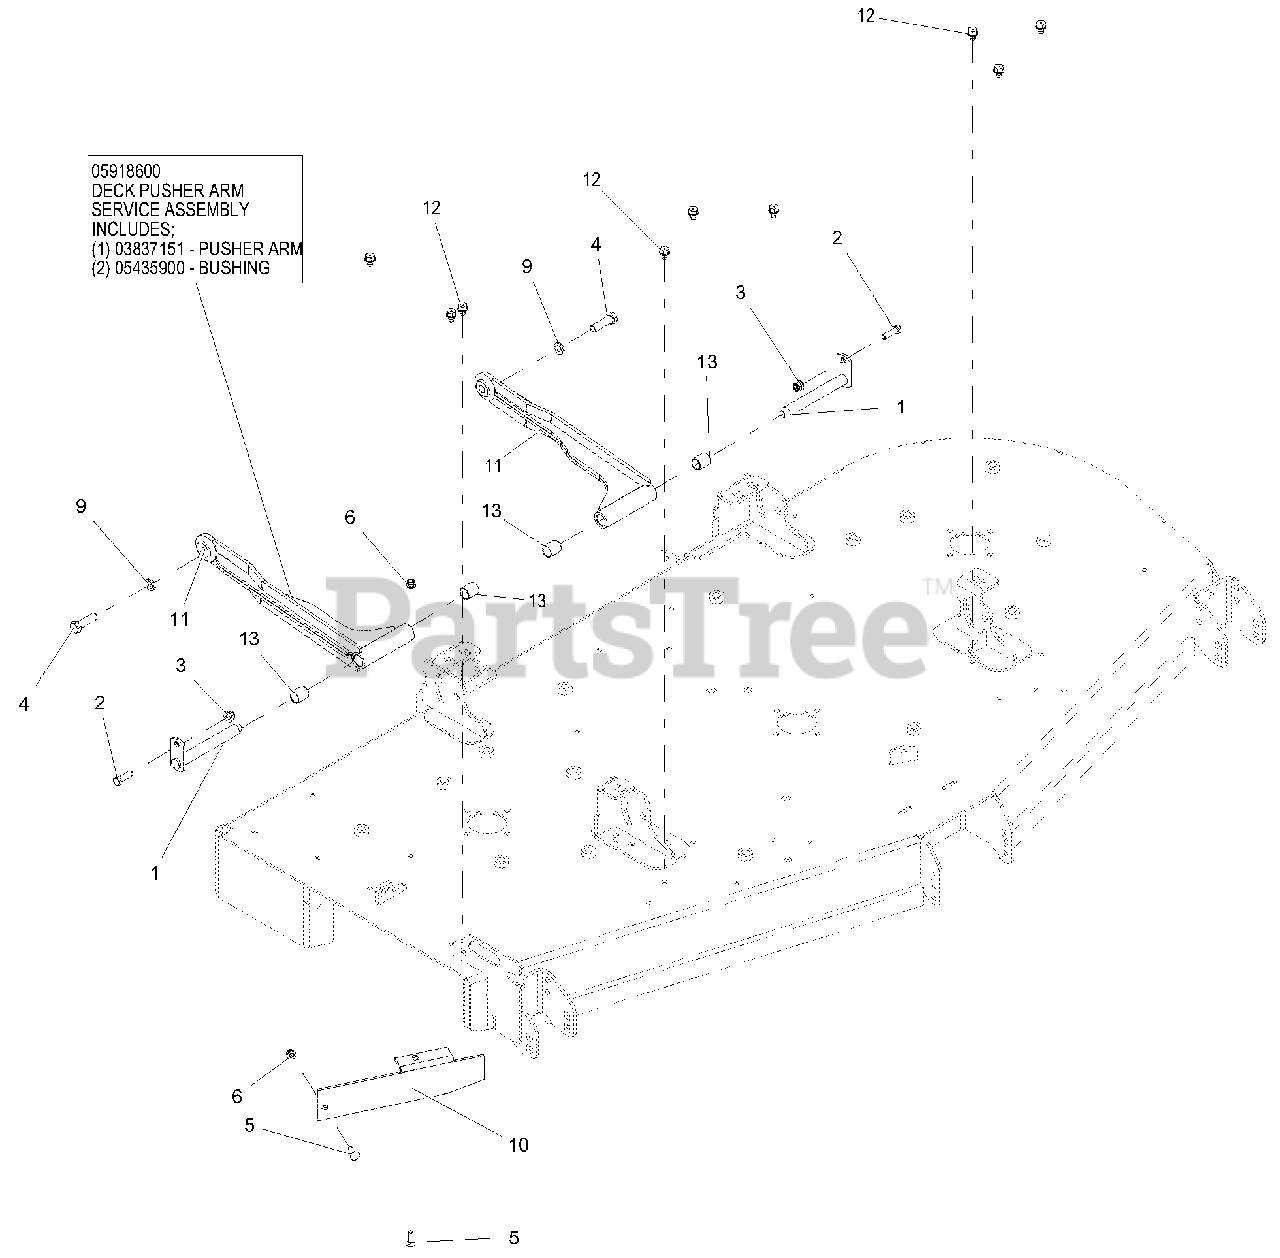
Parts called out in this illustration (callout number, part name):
1	WLDMT, MOWER MTG. PIN
2	BLT-HEX .38-16X1.25 GR5 YWZC
3	NUT-LK-NYL-FLG .38-16 YWZC
4	BLT-HEX .50-13X1.75 GR5 YWZC EP80
5	BLT-RDHDSQSHNK .31-18X1.00 G5 Y
6	NUT-LK-NYL-FLG .31-18 YWZC
9	WSHR-LK .50X.125 REG YWZC
10	BAFFLE, 72" DISCHARGE-RED
11	WMT, DECK STABILIZER ARM-BLACK
11	DECK PUSHER ARM SERVICE ASSEMBLY INCLUDES:
11	PUSHER ARM
12	SCR-TAP .38-16X.50 HWH TR YWZ
13	BRG, .750 X .875 X 1.000
